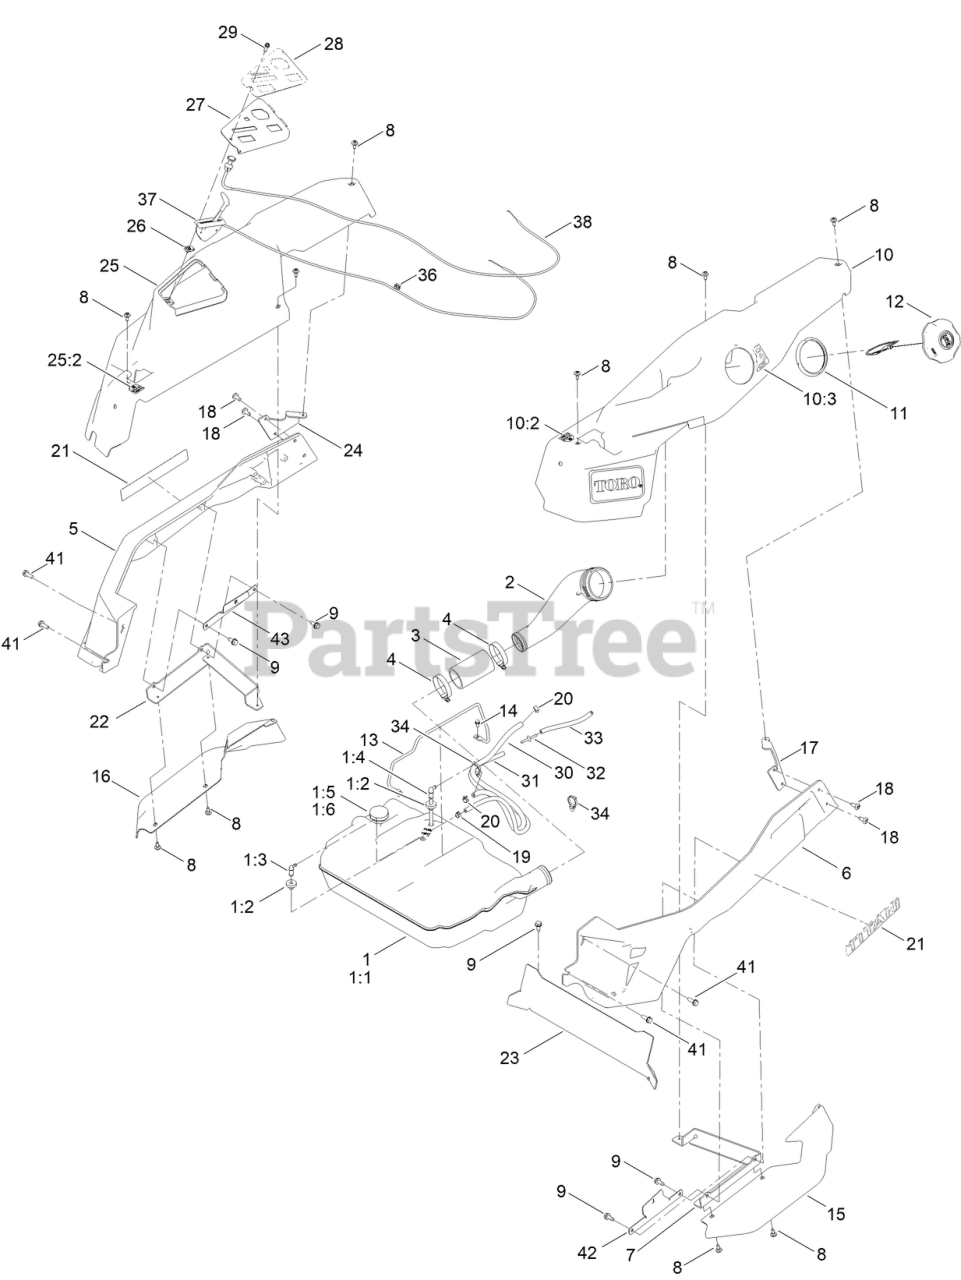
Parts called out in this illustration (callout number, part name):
1	TANK-FUEL, ASM
1:1	TANK-FUEL
1:2	BUSHING
1:3	FITTING-ELBOW 90
1:4	FITTING - PICKUP, FUEL
1:5	GROMMET-FUEL
1:6	REMOTE GAUGE ASM
2	NECK-FILLER, FUEL
3	HOSE-FILLER, FUEL
4	CLAMP-HOSE
5	CAST-TUBE, RH [RED]
6	CAST-TUBE, LH [RED]
7	MOUNT-POD BRACKET LH
8	SCREW-SHOULDER
9	SCREW-HWHTF
10	POD ASM - LH W/DECALS
10:2	DECAL-CONTROL LEVER, LH
10:3	DECAL-FUEL FILL
11	RING-RETAINING
12	CAP-FUEL, RATCHETING
13	ROD-HOLD DOWN
14	SCREW-HWH
15	FENDER-TIME CUTTER, LH
16	FENDER-TIME CUTTER, RH
17	BRACKET-REAR POD, LH
19	CLAMP-HOSE
20	CLAMP-HOSE
21	DECAL-TITAN
22	MOUNT-POD BRACKET RH
23	PLATE-KICK
24	MOUNT-POD BRACKET RH
25	POD ASM - RH W/DECALS
25:2	DECAL-CONTROL LEVER, RH
27	PANEL-CONTROL
28	DECAL - CONTROL PANEL
29	SCREW-HWHTF
30	HOSE-FUEL
31	HOSE-FUEL
32	ADAPTER ORIFICE
33	HOSE-VENT
34	CLIP-TIE
36	CLIP-HARNESS
37	CABLE-THROTTLE
38	CABLE-CHOKE
41	SCREW-TAPTITE
42	BRACKET-ALIGNMENT, POD LH
43	BRACKET- ALIGNMENT, POD RH
